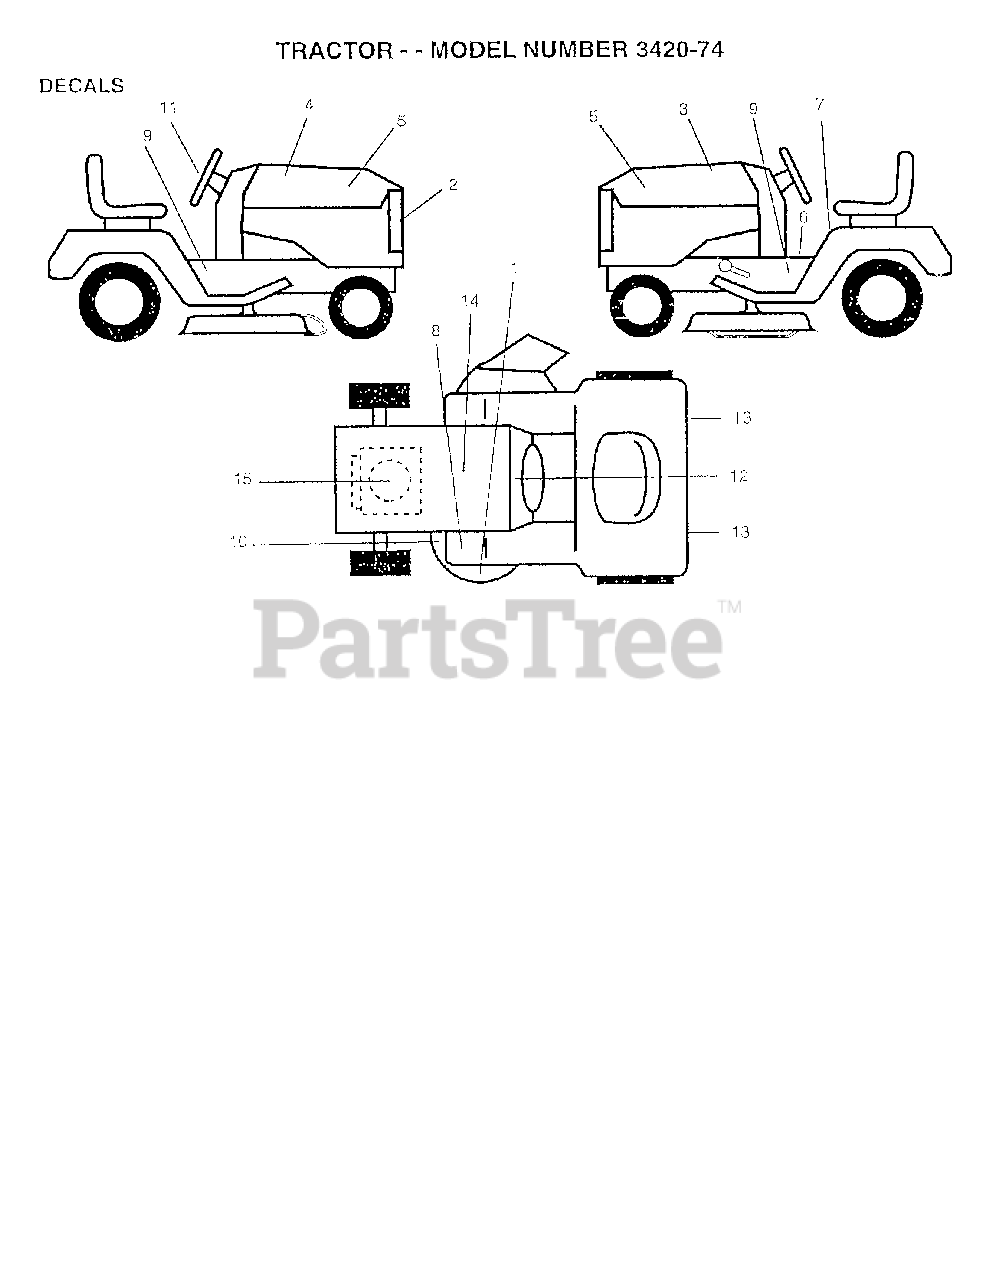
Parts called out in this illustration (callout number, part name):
2	Poulan TBD
3	Poulan TBD
4	Poulan TBD
5	Poulan TBD
6	DECAL PARK BRAKE
9	Poulan TBD
10	DECAL V-BELT SCHEMATIC
11	Poulan TBD
13	REFLECTOR-TAIL YT
14	Poulan TBD
15	Poulan TBD
